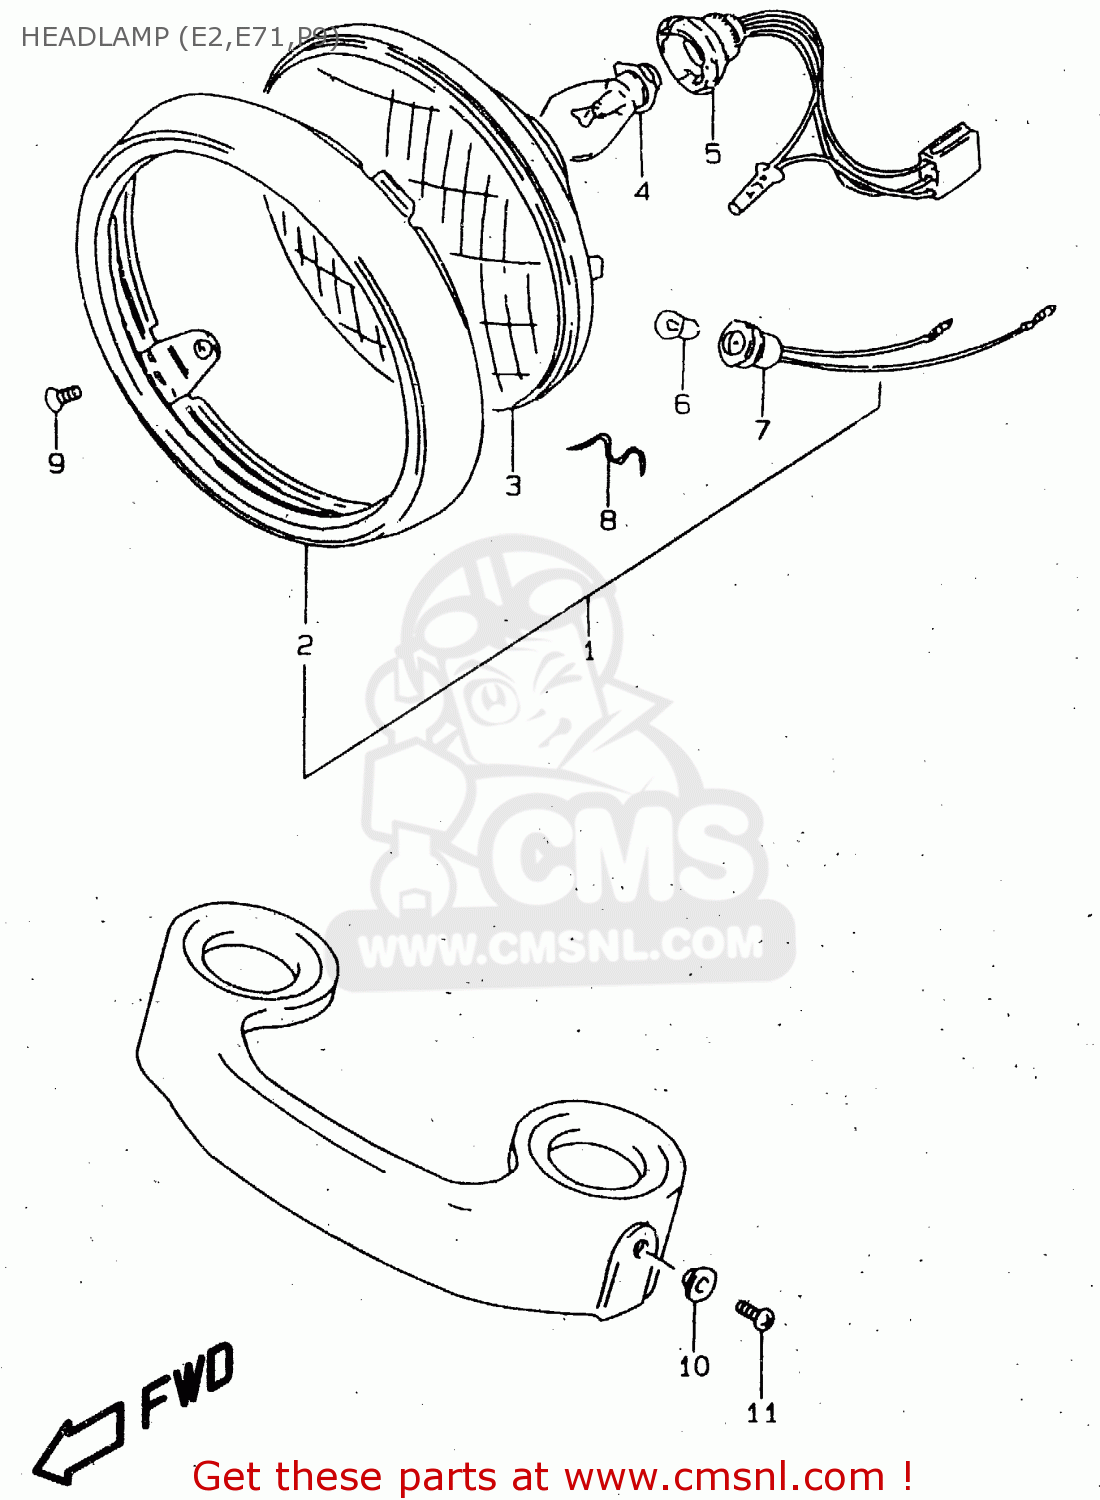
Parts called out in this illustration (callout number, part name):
1	HEADLAMP ASSY
2	RIM
3	LAMP UNIT
4	BULB
5	SOCKET
6	BULB(12V3.4W,STANLEY,A72A)
7	SOCKET
8	SPRING
9	SCREW
10	WASHER
11	SCREW
